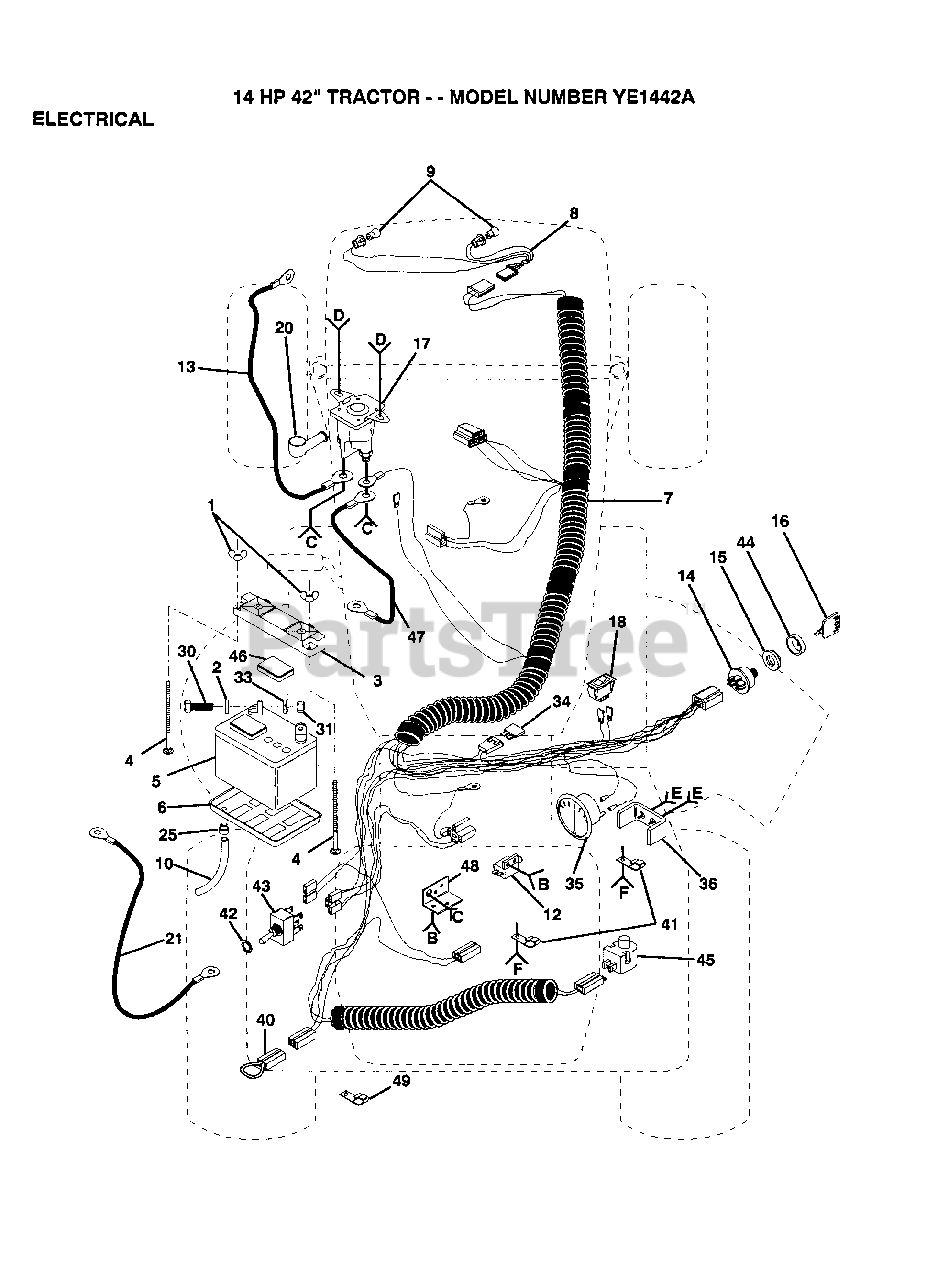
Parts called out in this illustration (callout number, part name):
2	WASHER
4	BOLT
9	HEADLAMP BULB
12	SWITCH-INTER. GT
13	"CABLE T, BATTERY"
15	NUT IGNITION
16	KEY
18	SWITCH LT
21	CABLE T
25	HOSE CLAMP T
30	BOLT LT
33	LOCKWASHER
34	FUSE HYT
35	AMMETER T
41	CLIPT
42	HEX NUT T
45	SWITCH SEAT
46	"CAP,BATTERY "
47	CABLE-BATTERY T
48	BRACKET LT
49	CLIP T
